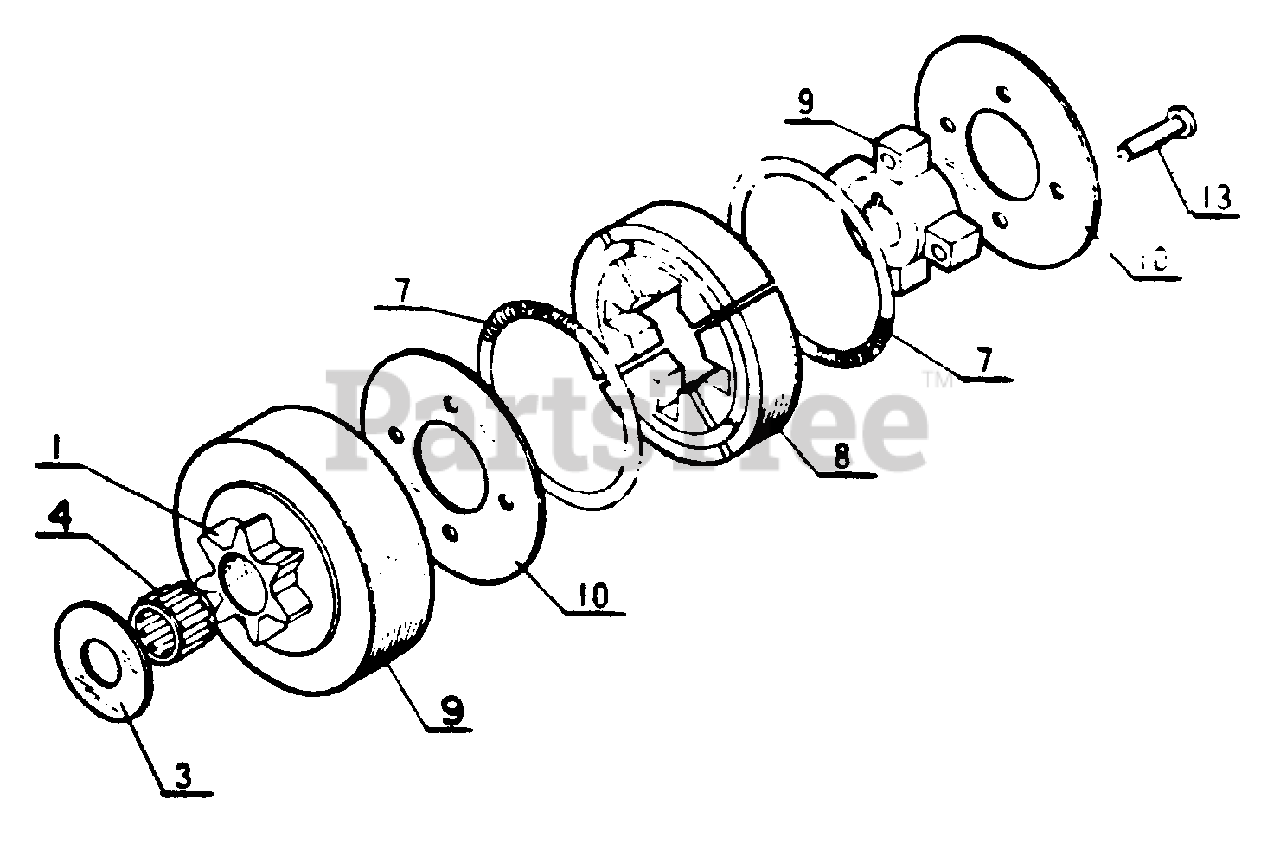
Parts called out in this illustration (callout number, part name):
1	DRUM, CLUTCH
3	WASHER, CLUTCH
4	BEARING, NEEDLE
7	SPRING, CLUTCH
8	SHOE, CLUTCH
9	HUB, CLUTCH
10	PLATE, CLUTCH
13	RIVET
